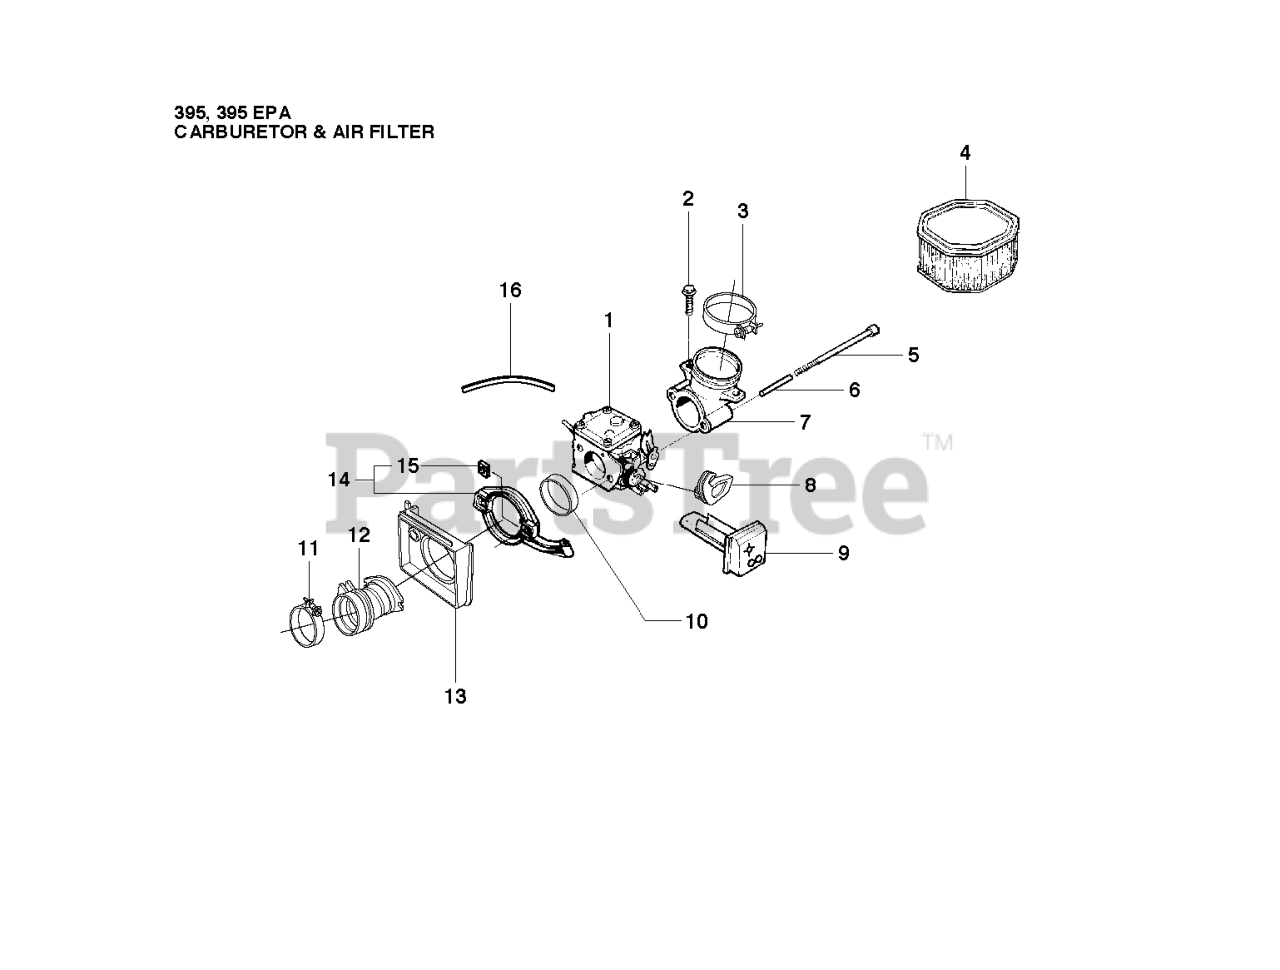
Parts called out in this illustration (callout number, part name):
1	CARBURETOR
2	SCREW IHSCFM
3	CLAMP 41MM
4	AIR FILTER HD 80
4	AIR FILTER FELT
4	AIR FILTER HD 44
7	CONNECTION
11	CLAMP 39MM
12	INLET PIPE
